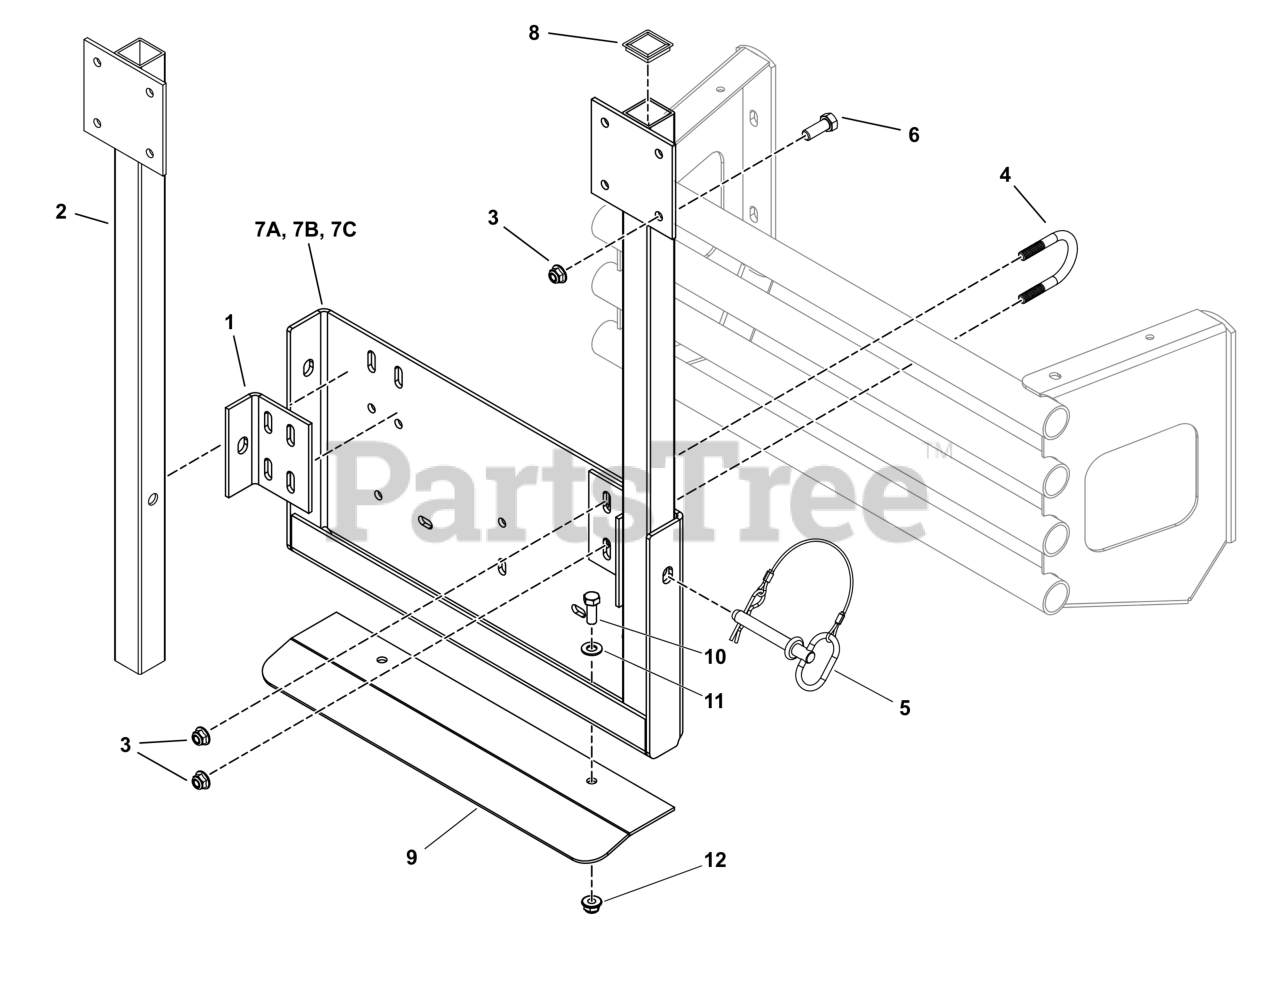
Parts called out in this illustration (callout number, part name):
1	MOUNT, TAB, BLACK
2	WELD, MOUNT, POST - BLK
3	NUT, 3/8-16 HEX NYLOCK FLANGE
4	U-BOLT, 3/8 X 1-1/4
5	PIN, HITCH, .50 X 3.25 W/ LAY
6	BOLT, 3/8-16 X 1" GD5 CZ
7A	WELD, BAGGER MNT
7C	WELD, 3-BAG MOUNT, ALL - BLK
8	CAP, PLASTIC, 1-1/2" X 1-1/2
9	PLATE, BAGGER MOUNT, DEFLECTOR - BLK
10	BOLT, 3/8-16 X 1" GD5 CZ
11	WASHER, 3/8 SAE
12	NUT, 3/8 - 16 HEX NYLOCK FLANGE
